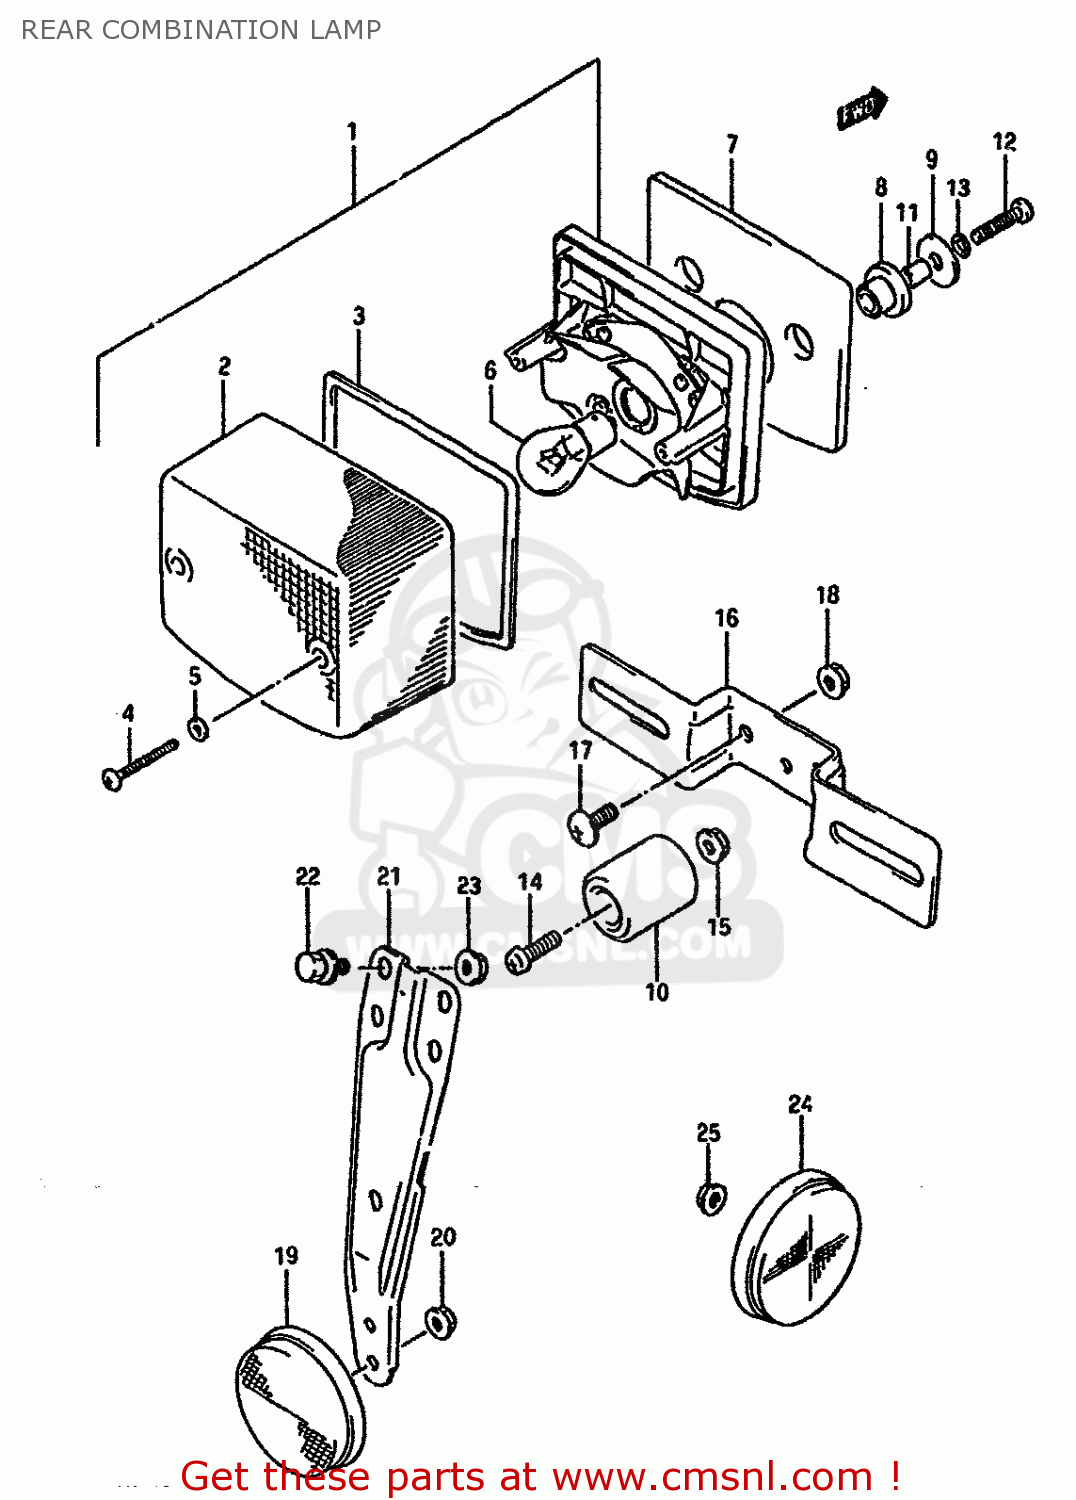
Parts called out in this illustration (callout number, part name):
1	LAMP ASSY,REAR COMBINATION
2	LENS
3	GASKET (NAS)
4	SCREW
5	GASKET (NAS)
6	BULB(12V21/5W)
7	CUSHION
8	CUSHION,REAR COMBINATION LAMP
9	WASHER,REAR COMBINATION LAMP
10	CUSHION
11	SPACER
12	SCREW
13	WASHER,LOCK
14	SCREW
15	NUT
16	BRACKET,LICENSE PLATE
17	SCREW
18	NUT
19	REFLEX REFLECTOR,RR
20	NUT 5MM
21	BRACKET
22	BOLT
23	NUT
24	REFLEX REFLECTOR
25	NUT 5MM
